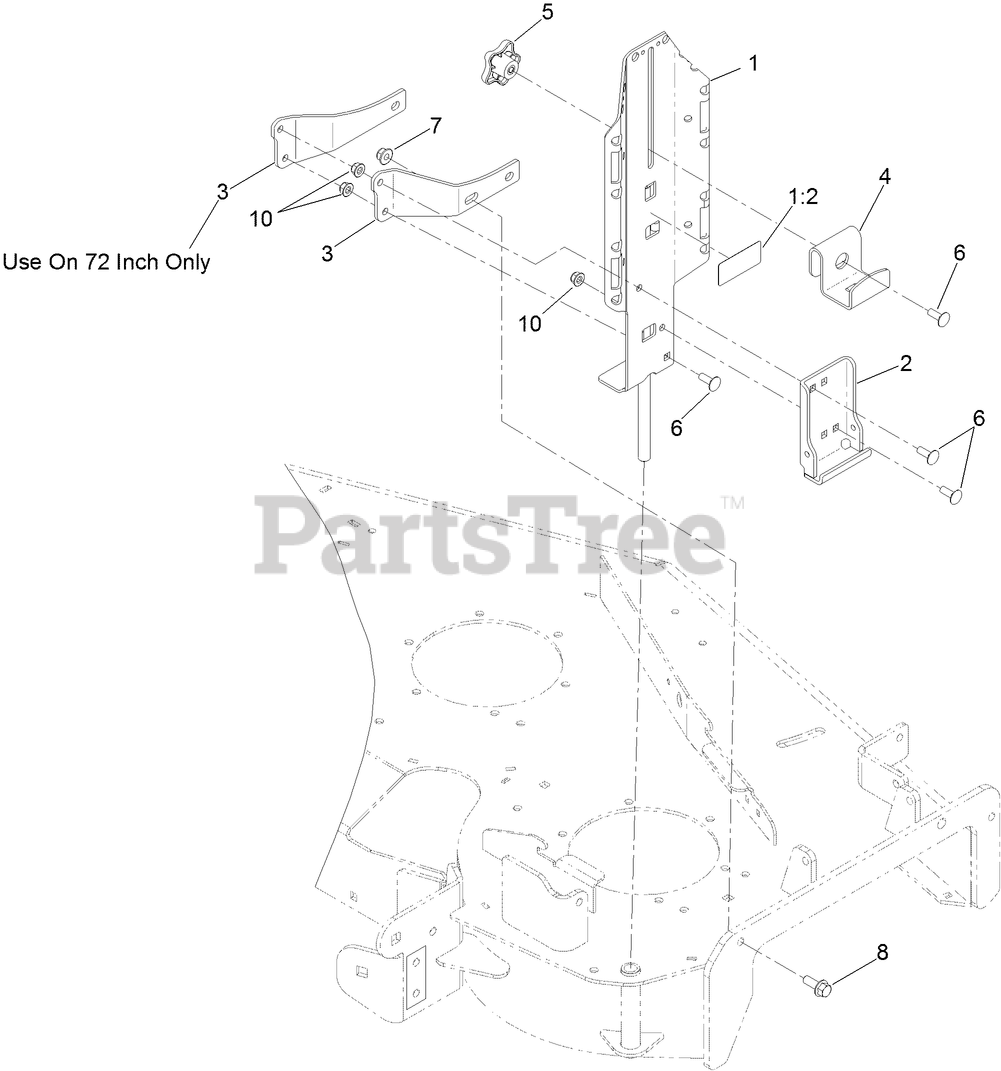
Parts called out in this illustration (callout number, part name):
1	BUCKET MOUNT HOLDER ASM
1:2	DECAL-WEIGHT, MAXIMUM
2	BRACKET-SUPPORT, HINGE
3	STRAP-MOUNT
3	STRAP-MOUNT (72IN DECK ONLY)
4	BRACKET-TOP
5	KNOB-HANDLE
6	BOLT-CARR
7	NUT-HF, NI
8	SCREW-HHF
10	NUT-HF, NI
